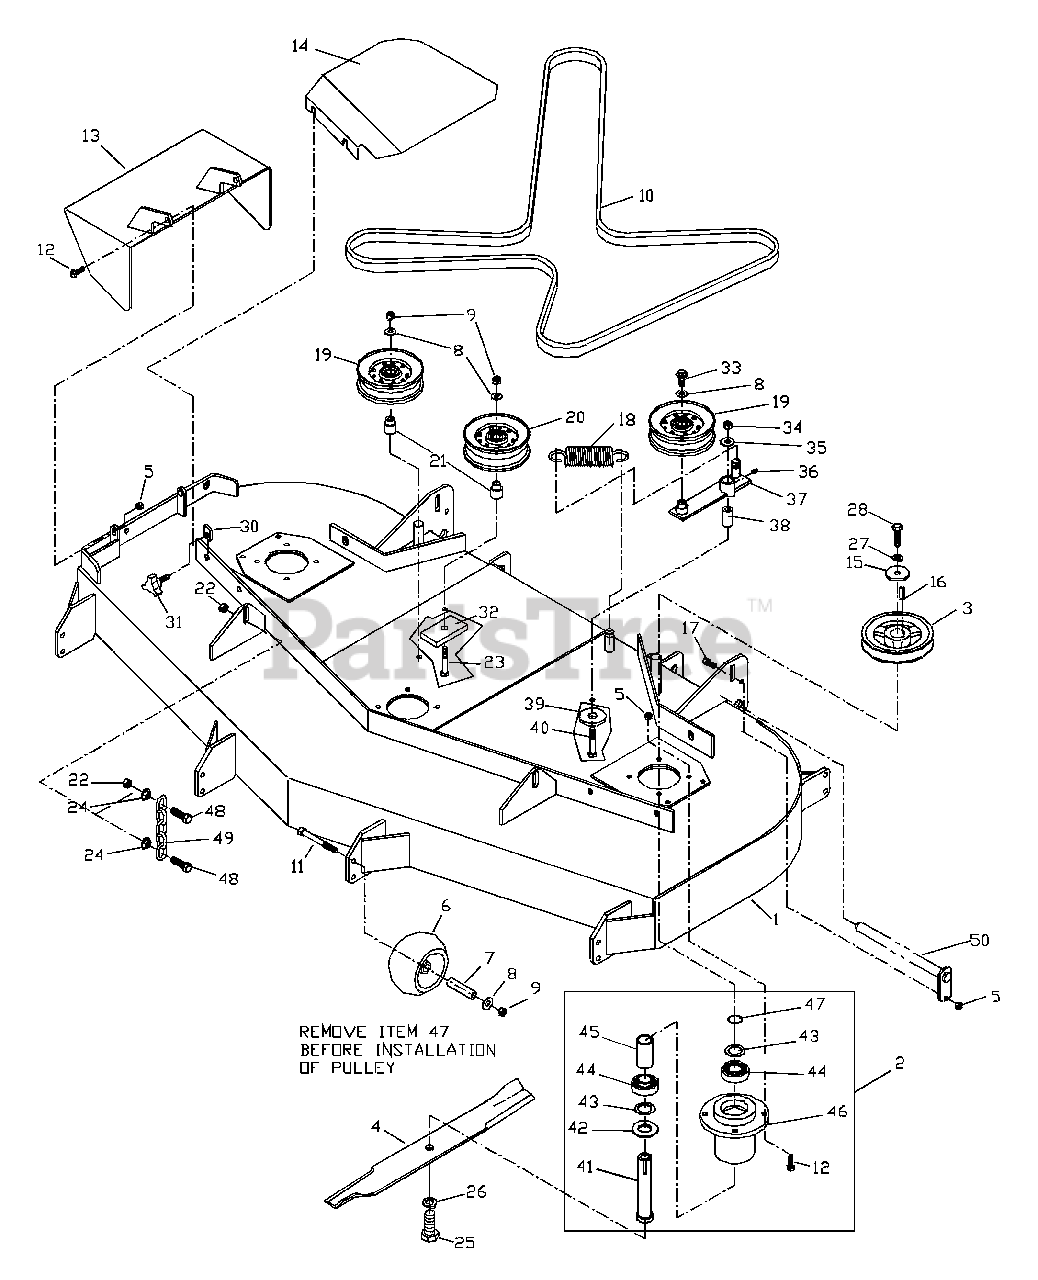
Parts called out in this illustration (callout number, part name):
1	61" DECK W/ DECALS
1	52" DECK W/ DECALS
2	CUTTER HOUSING ASM.
3	PULLEY 61" DECK
3	PULLEY 51" DECK
5	NUT 5/6C CENTERLOCK
8	WASHER 3/8 STD.
9	NUT 3/8C CENTERLOCK
10	BELT 61"
10	BELT 52"
11	HCS 3/8C X 3.5
12	HCS 5/16C X 1
13	DISCHARGE CHUTE
14	BELT SHIELD RT. 61"
14	BELT SHIELD RT. 52"
16	KEY 1/4SQ. X 1 1 /8
17	HCS 5/6C X 3/4
19	IDLER PULLEY (1.31)
20	IDLER PULLEY (1.62)
21	IDLER SPRING
22	NUT 7/16C CENTERLOCK
23	HCS 3/8C X 2.5
24	7/16C WHIZ NUT
25	HCS 5/8F X 1.25
27	7/16 LOCK WASHER
28	HCS 7/16F X 1.5
29	BELT SHIELD LT. 61"
29	BELT SHIELD LT. 52"
31	KNOB W/ STUD
32	PAD
33	HCS 3/8C X 1 SERR.
34	NUT 1/2C NYLOC
35	1 /2 FLAT WASHER
36	ZERK
38	PIVOT BUSHING
39	SUPPORT WASHER
40	HCS 1/2C X 3.25
42	MACH. BUSHING 10GA.
43	MACH. BUSHING 18GA.
44	BEARING
48	HCS 7/16C X 1.5
49	LIFT CHAIN
